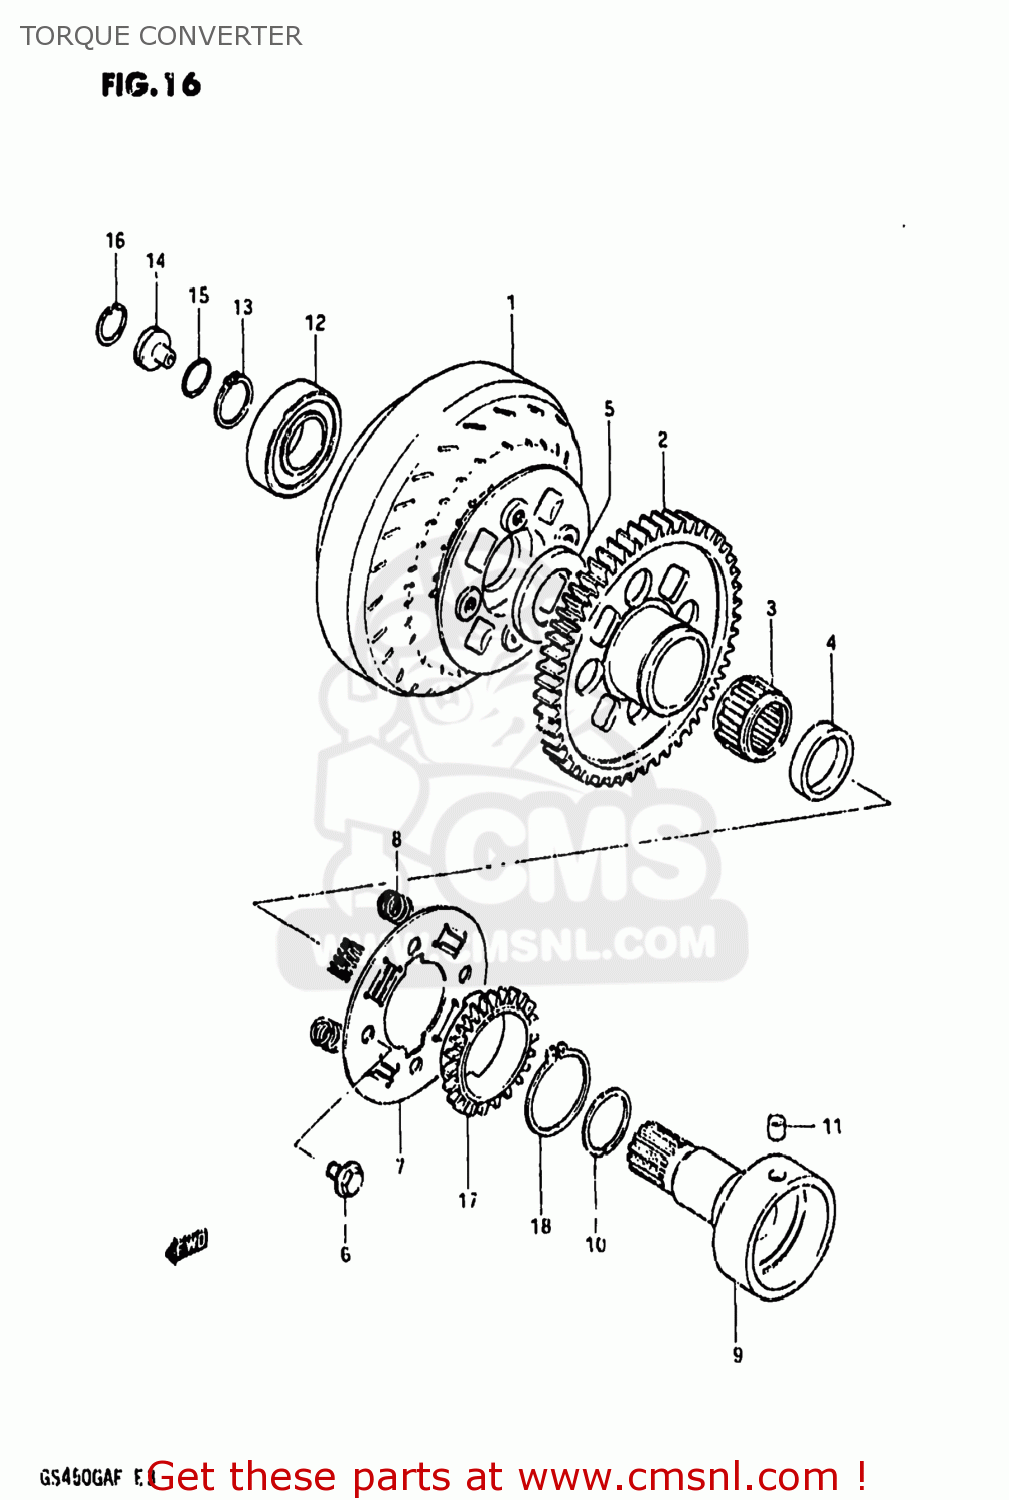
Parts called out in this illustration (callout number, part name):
1	GEAR ASSEMBLY,PRIMARY DRIVE
2	GEAR,PRIMARY DRIVEN
3	ROLLER BEARING (26X34X1
4	SPACER
5	SHIM
6	BOLT
8	SPRING
10	SPACER,PRIMARY DRIVEN
11	PIN
12	BEARING
13	CIRCLIP,25MM
15	O-RING (D:1.5 ID:15.2)
16	CIRCLIP
17	GEAR,OIL PUMP DRIVE
18	CIRCLIP
